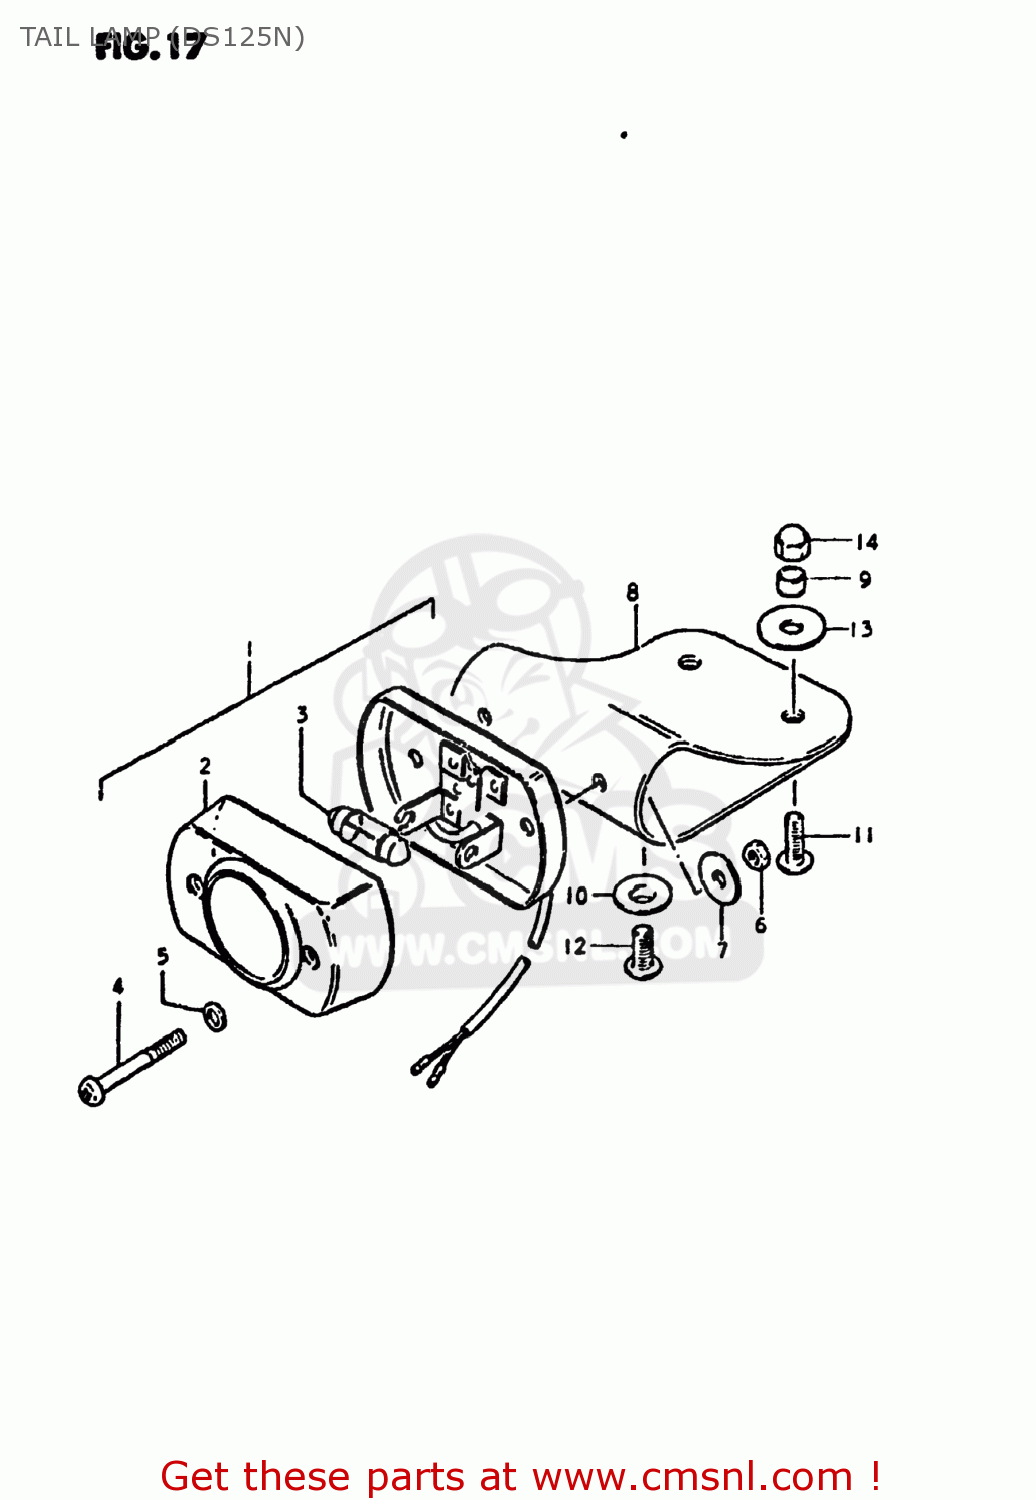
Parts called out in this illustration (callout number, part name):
1	LAMP ASSEMBLY,REAR COMBINATION
2	LENS,REAR COMBINATION LAMP
3	BULB
4	SCREW,REAR COMBINATION LAMP LENS
5	WASHER,REAR COMBINATION LAMP
6	NUT
7	WASHER(5.2X16X1)
8	CUSHION,REAR COMBINATION LAMP
9	SPACER(6.2X8.3X5.7)
10	WASHER
11	SCREW
12	SCREW 6X12
13	WASHER (6.5X20X1.2)
14	NUT
